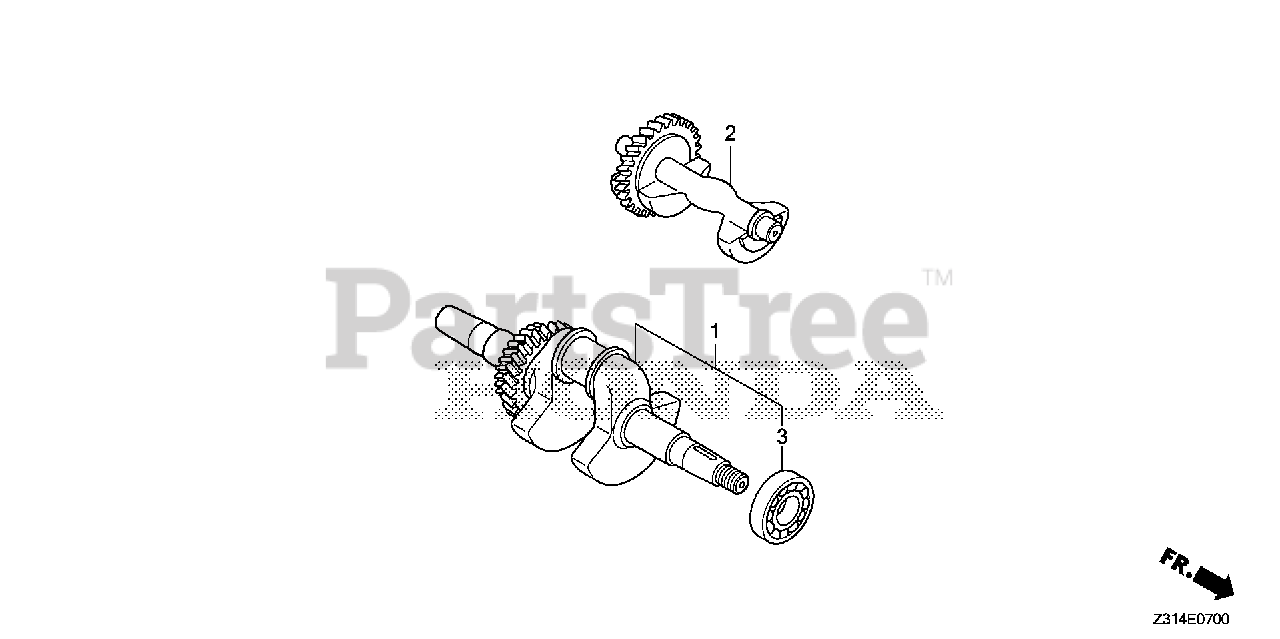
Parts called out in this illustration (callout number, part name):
1	CRANKSHAFT
2	WEIGHT, BALANCER
3	BEARING, RADIAL BALL (6207SH)
